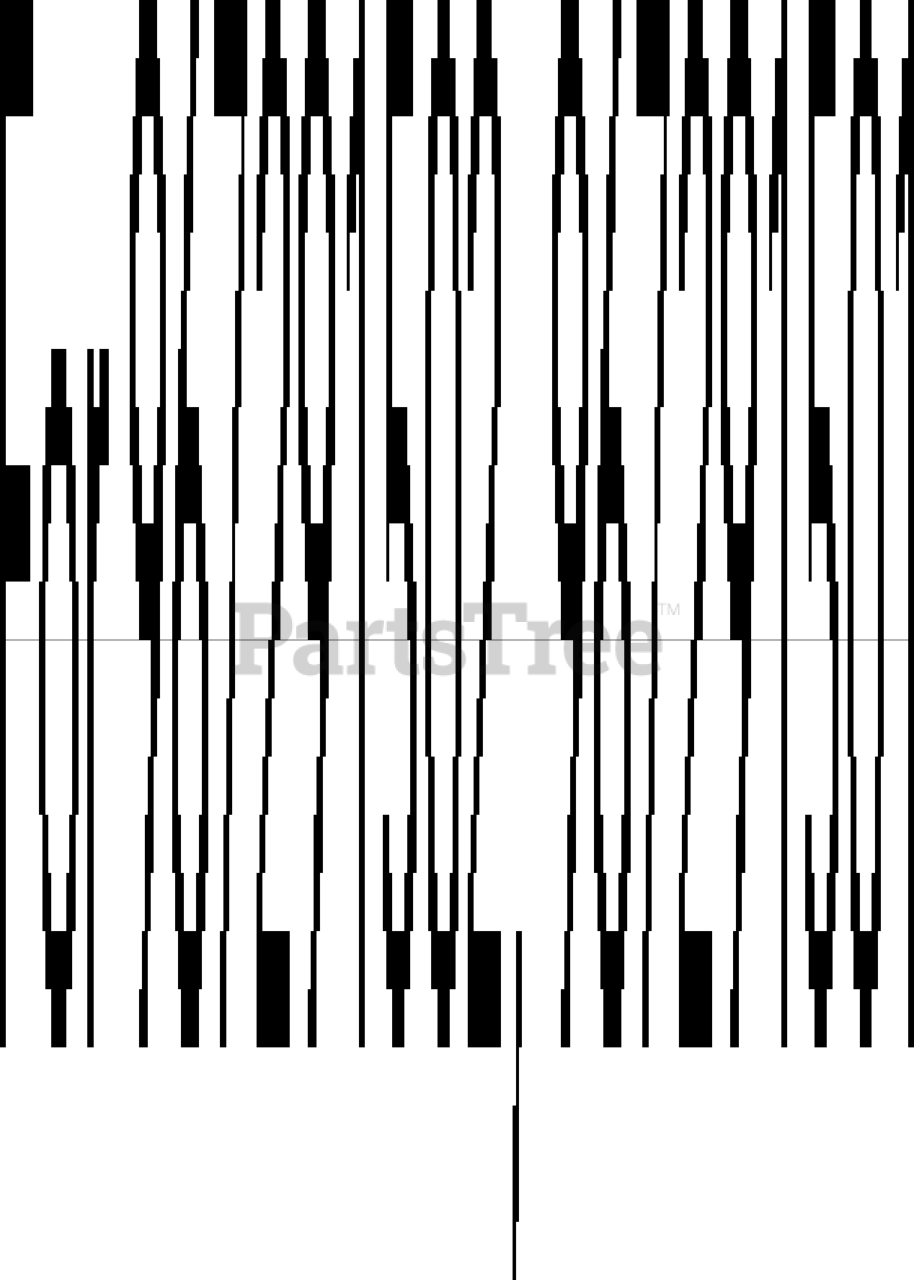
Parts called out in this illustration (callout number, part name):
48	LOCKNUT M8
53	NUT
55	PIVOT WHEEL ASSY
59	LOCKNUT M8
60	DECK ROLLER, FRONT
62	RETAINING RING SGA 15
66	SCREW
68	COLLAR SCREW
69	CLIP GRAY
70	SCREW
